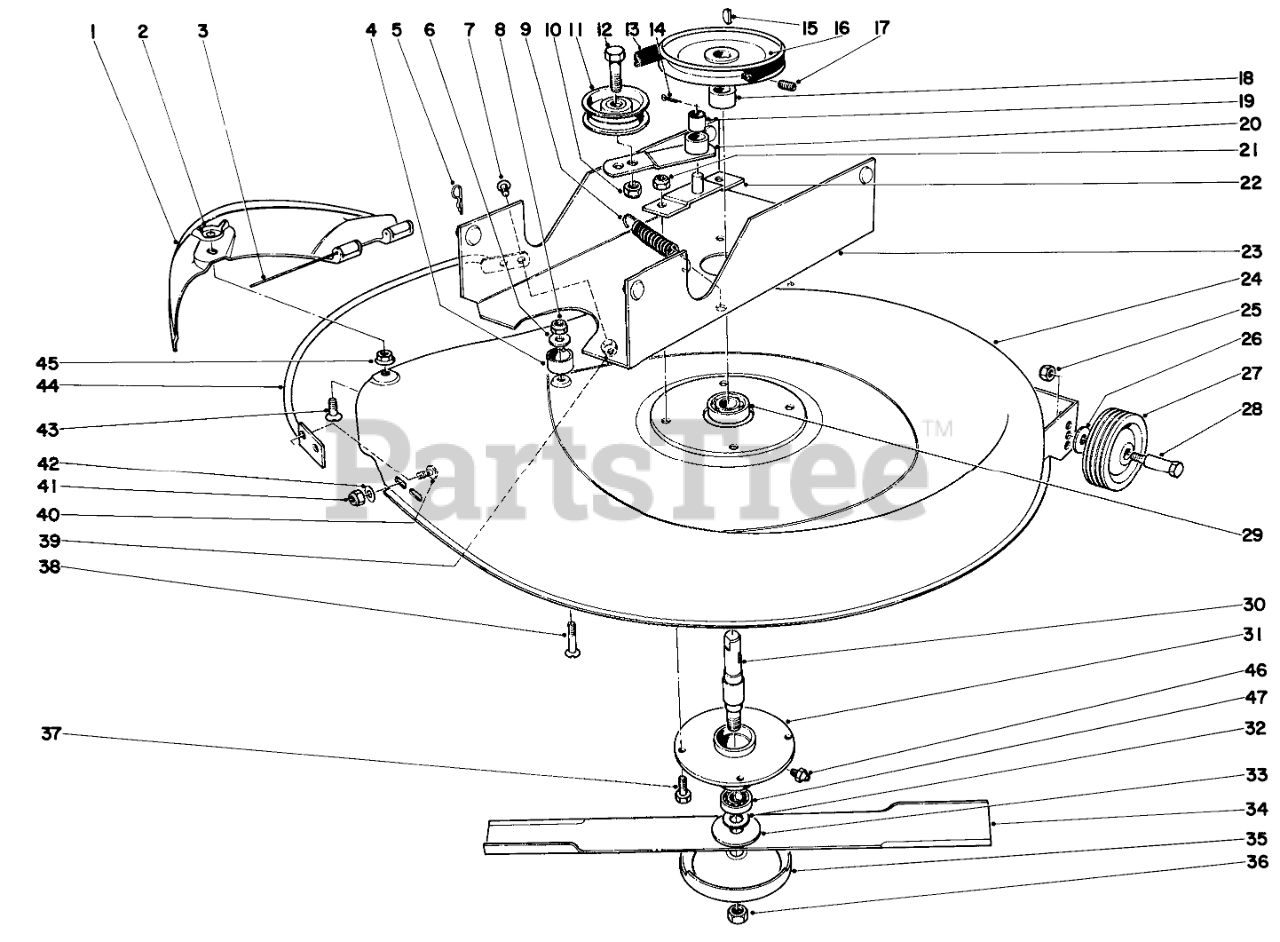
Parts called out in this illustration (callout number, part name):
1	DEFLECTOR
2	Wing Nut
3	Hinge Pin
4	Spacer
5	PIN-COTTER
6	WASHER-FLAT
7	5/16-18X5/8 TRS HD MS
9	Spring
11	Idler Pulley
12	SCREW-HH
13	FRONT PULLEY BELT
14	PIN-COTTER
15	KEY-WOODRUFF
16	PULLEY
17	SCREW-HSH
18	Spacer
19	Bushing
20	Idler Plate
21	Nut
22	Pivot Bracket
23	Channel
24	Housing
26	WASHER-FLAT
27	Wheel
29	Bearing
30	Blade Spindle
31	MOWER SPINDLE HOUSING
32	WASHER
33	WASHER
34	Blade
35	Cup
37	SCREW-HH
38	Screw
39	Nut
42	WASHER-FLAT
43	5/16-18X7/8 FLT HD MS
45	PAL NUT
46	FITTING-GREASE
47	.6693 RP BALL BEARING
